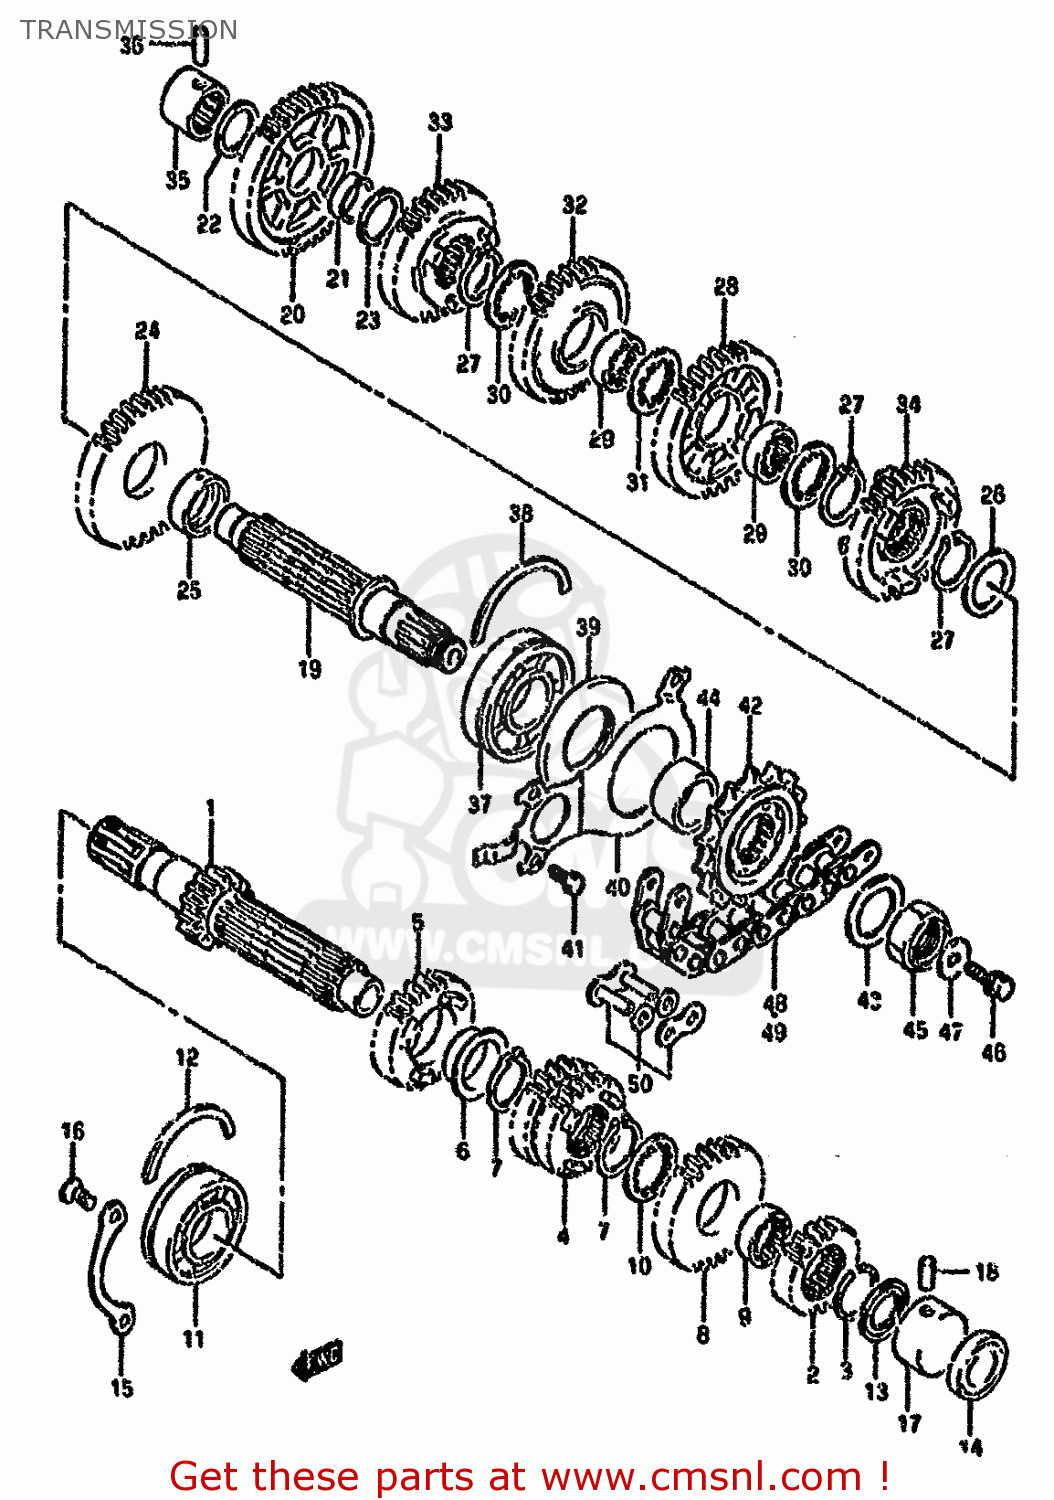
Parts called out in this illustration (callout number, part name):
1	SHAFT,COUNTER
2	GEAR,SECOND DRIVE
3	CIRCLIP
4	GEAR,THIRD & FOURTH DRIVE
5	GEAR,FIFTH DRIVE
6	BUSH(28X32X2)
7	CIRCLIP
8	GEAR,SIXTH DRIVE
9	BUSHING,SIXTH DRIVE GEAR
10	WASHER,LOCK
11	BEARING(25X62X17)
12	C-RING
13	SEAL,OIL(20X31.2X2.7)
14	CAP,COUNTER SHAFT,L
15	RETAINER,CNTR SHAFT BEARING
16	SCREW
17	BEARING(20X34X17.5)
18	PIN
19	SHAFT,DRIVE
20	GEAR,1ST DRIVEN(NT:43)
21	BUSH(22X26X9)
22	WASHER
23	WASHER
24	GEAR,2ND DRIVEN
25	BUSHING
26	WASHER, THRUST
27	CIRCLIP
28	GEAR,3RD DRIVEN(NT:33)
29	BUSH,3RD DRIVEN GEAR
30	WASHER,LOCK
31	WASHER,LOCK
32	GEAR,FOURTH DRIVEN
33	GEAR,5TH DRIVEN(NT:29)
34	GEAR,6TH DRIVEN
35	BEARING(20X34X20)
36	PIN
37	BEARING(28X70X18)
38	C RING
39	SEAL,OIL(34.8X70X6)
40	RETAINER,DRIVE SHAFT OIL SEAL
41	BOLT
42	SPROCKET,ENGINE (NT:15)
43	WASHER,THRUST
44	SPACER(25X36X17.7)
45	NUT
46	BOLT
47	WASHER
48	CHAIN ASSEMBLY,DRIVE 50GSV
49	CHAIN ASSEMBLY RK50GSVZ1.1
50	JOINT SET,DRIVE CHAIN
